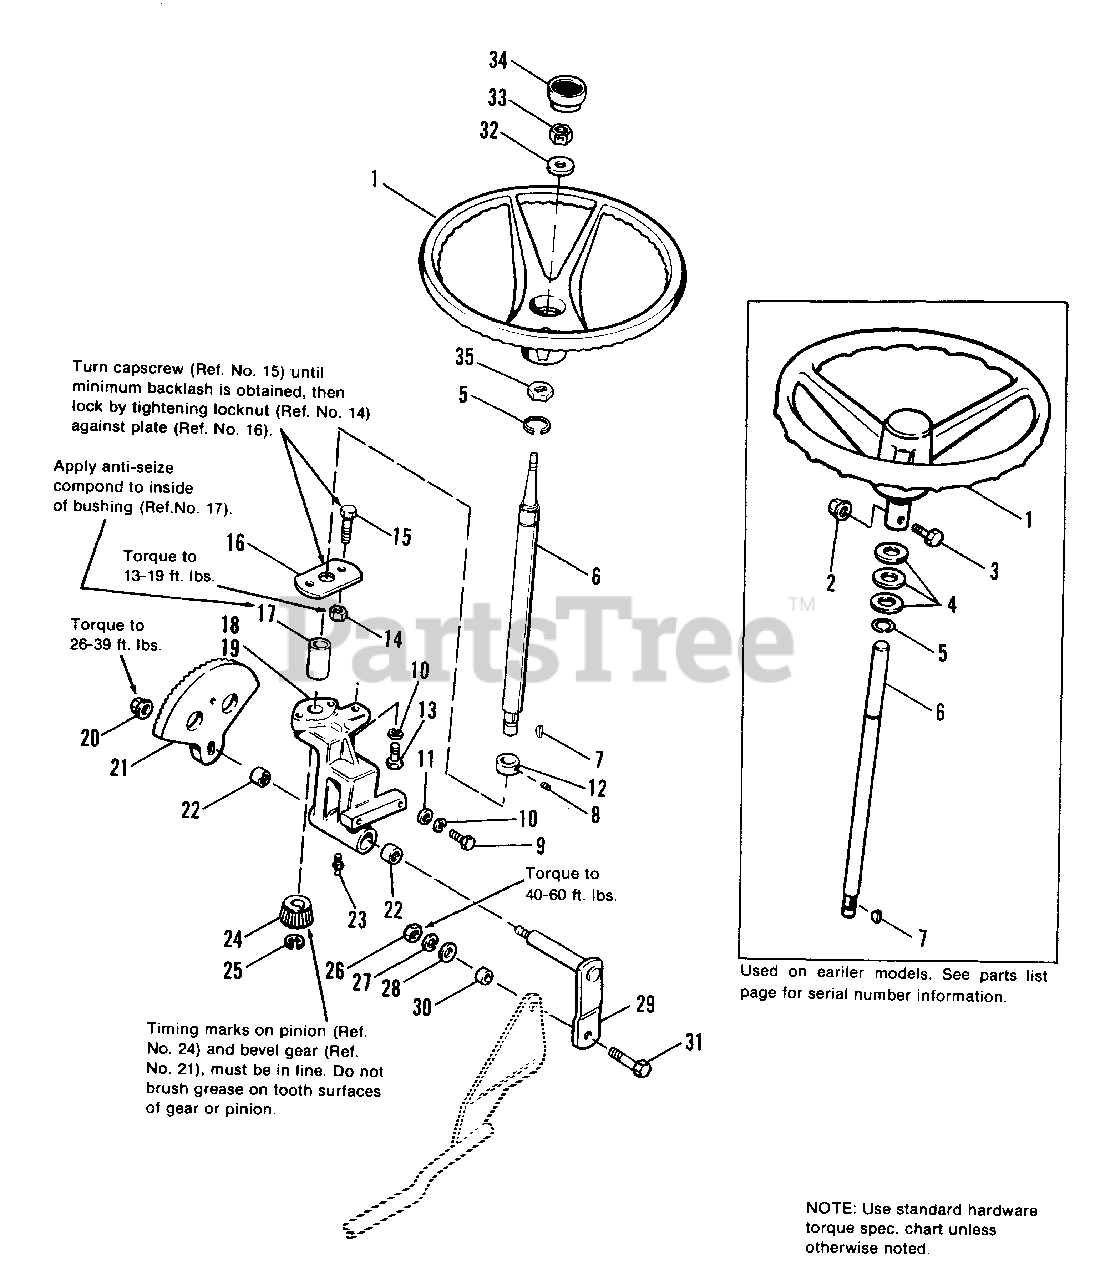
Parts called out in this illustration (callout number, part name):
1	WHEEL, Steering
2	LOCKNUT, Hex, Flange, 5/16-18
3	CAPSCREW, Hex Hd., 5/16-18 x 1-1/4
4	WASHER
5	RING, Retaining
6	SHAFT, Steering
7	KEY, Woodruff. #6
8	SETSCREW. 5/16-18 x 1/4
9	CAPSCREW, Hex Hd., 3/8-16 x 7/8
10	LOCKWASHER, 3/8
11	WASHER, Plain, 3/8
12	COLLAR, Set
13	CAPSCREW, Hex Hd., 3/8-16 x 3/4
14	LOCKNUT, Hex, Jam, 3/8-16
15	CAPSCREW, Hex Hd., 3/8-16 x 1-1/4
16	PLATE, Steering
18	HOUSING ASSY., Steering (Includes Ref. Nos. 17 & 22)(Used with 1667691)
18	HOUSING ASSY., Steering (Includes Ref. Nos. 17 & 22)(Used with 171020)
19	HOUSING ASSY., Steering
20	LOCKNUT, Hex, Flange, 7/16-14
21	GEAR, Bevel
22	BEARING, Needle
23	FITTING, Grease
24	PINION, Bevel
25	E-RING
26	NUT, Hex, Full, 1/2-13
27	LOCKWASHER, 1/2
28	WASHER, Plain, 1/2
29	ARM ASSY., Steering
31	CAPSCREW, Hex Hd., 1/2-13 x 1-1/2
32	WASHER, Compression
33	LOCKNUT, Hex, Cntr., 5/16-18
34	CAP, Steering Wheel
35	SHAFT, Steering
35	WASHER, Hex
